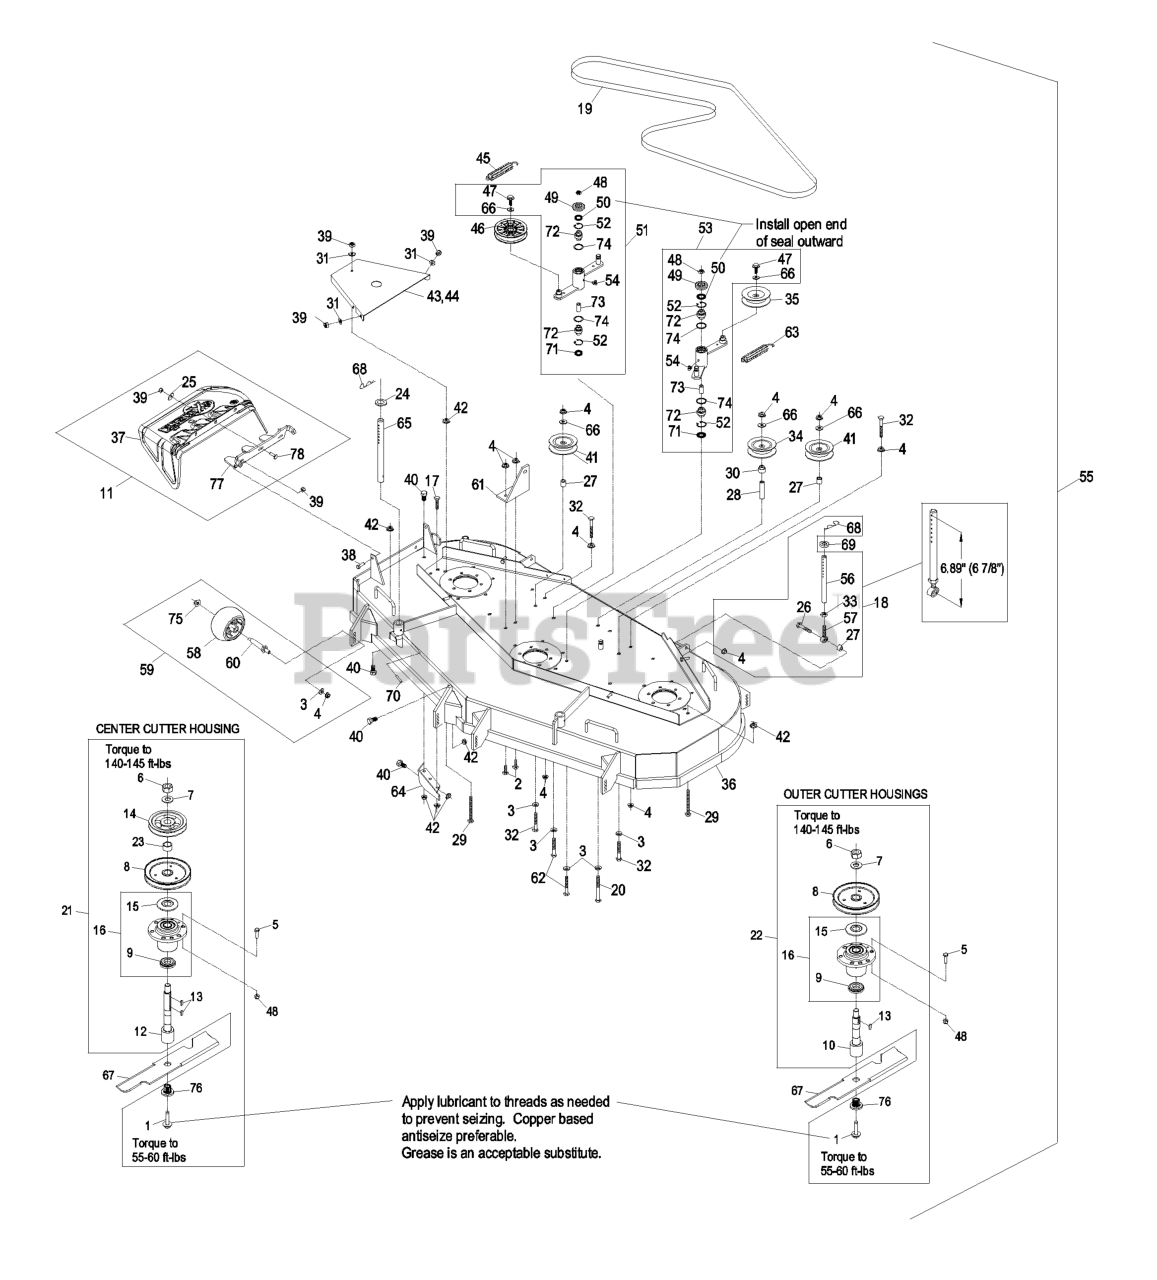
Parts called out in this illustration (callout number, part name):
2	SCREW-HH
3	WASHER-BELLEVILLE
4	NUT-HHF, WHIZ
5	SCREW-HH
8	SHEAVE,BLADE DRIVE 6.30
9	SPACER-GUARD, BOTTOM
10	KIT, SPLINED SPINDLE 103-
11	ASM,FMD DISCHARGE CHUTE
12	KIT, SPLINED SPINDLE 103-
14	SHEAVE,BLADE DRIVE
15	GUARD-BEARING, TOP
16	KIT, CUTTER HOUSING
17	SCREW-HH
18	KIT,SUPPORT LINK W/PIN
19	BELT,MULE DRIVE
20	SCREW-HH
21	ASM, CUTTER HSG FMD604CTR
22	ASM, CUTTER HSG COMPLETE
23	SPACER,TUBE
24	SPACER-DECK SUPPORT
25	WASHER-FLAT
26	SCREW-HH
28	SPACER-ANCHOR, CLUTCH
29	BOLT,TAP HH
30	BUSHING,IDLER
31	WASHER-FLAT
32	BOLT-CARR
33	NUT-HJ
34	PULLEY-IDLER
35	PULLEY-IDLER
37	CHUTE,DISCHARGE
38	SCREW-HH
39	NUT-LOCK, NI
40	SCREW-HH
41	IDLER,PULLEY
43	SHIELD,BELT RH
44	SHIELD,BELT LH
45	SPRING-EXTENSION
46	PULLEY-IDLER, FLAT
47	SCREW-HHF
48	NUT-LOCK, NI
49	GUARD-TOP
50	SEAL-LIP, SINGLE
51	KIT, IDLER ARM W/BEARINGS
52	RING-SNAP
53	KIT, IDLER ARM W/BEARINGS
54	FITTING-GREASE, 90 DEG
55	Complete Deck Assy
56	LINK,SUPPORT
57	BALLJOINT
58	ROLLER-SCALP, ANTI
61	BRACKET,SPRING ANCHOR
62	SCREW-HH
63	SPRING-EXTENSION
64	WLD,BAFFLE DISCHARGE
65	ROD,DECK SUPPORT
66	WASHER-FLAT
68	PIN,HAIR COTTER
71	SEAL-LIP, DOUBLE
72	BEARING-SPHERICAL
73	BUSHING-LEVER, LIFT
75	Nut-Nyloc 3/8-16 Flg
76	BUSHING,SPLINED
77	BRACKET, DISCHARGE CHUTE
78	SCREW-CARR
